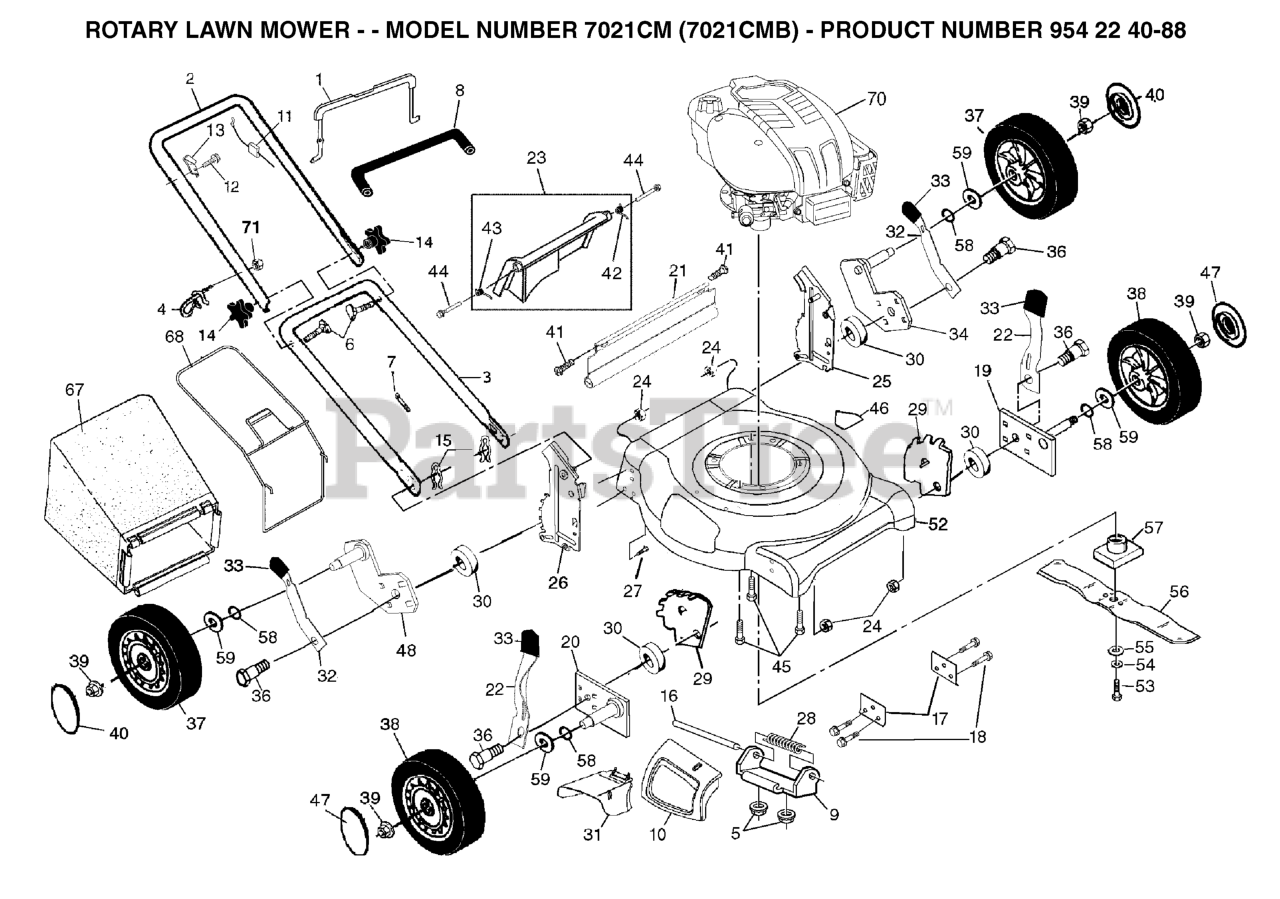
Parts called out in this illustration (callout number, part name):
1	CONTROL BAR
2	UPPER HANDLE, WITH GRIP
3	HANDLE.LOWER.GREY
4	ROPE, GUIDE
5	LOCKNUT.NYLOC.1/4-20
6	HANDLE BOLT
7	TIE GUIDE
8	GRIP.HANDLE.FOAM
9	BRACKET.ASM.HOUSING.EZ.MUL
10	RP DOOR.MULCH.21".REAR.PUSH.GR
11	ENGINE ZONE CONTROL CABLE
13	BRACKET
14	KNOB.HANDLE.STAR.HUSQ.GRAY
15	HAIRPIN COTTER
16	ROD.HINGE.COMBI-C
17	SUPPORT BRACKET
18	SCREW 1/4X20
19	AXLE ARM ASSY LF
20	AXLE ARM ASSY
21	REAR SKIRT
22	REPL BY 532 1683-60
23	KIT.REAR.DOOR.21.DOMED.
24	NUT.CENTERLOCK.5/16-
25	HANDLE BRACKET ASSEMBLY, LEFT
26	HANDLE.BRKT.ASSY.RIGHT.BLACK
27	SCREW
28	TORSION SPRING
29	WHEEL BRACKET ADJUSTER
30	SPACER.34X1.38X.22
31	DEFLECTOR.CLIPPING.21.GREY
32	SELECTOR SPRING, REAR
33	SELECTOR KNOB
34	AXLE ARM ASSY 10"
36	SHOULDER BOLT
37	WHEEL.10X2.PR.HITRAC.BLACK
38	WHEEL 8 X 2 BLACK BALL BEARING
39	HEX FLANGE LOCKNT
40	HUBCAP.10.MAG.SILVER
41	HINGE SCREW
42	SPRING (LH)
43	SPRING (RH)
45	BOLT 3/8-16X1-1/8
46	DECAL HYT
47	HUBCAP
48	ARM ASM AXLE 10"
52	HOUSING ASSEMBLY
53	SCREW, HEX HD 3/8-24 X 1-3/8
54	LOCKWASHER
55	WASHER,HARDEN
56	BLADE.21.PUSH/RWGD/FWG
57	BLADE ADAPTER
58	O-RING
59	WASHER.FLAT.1/2
67	GRASS BAG
68	FRAME, GRASS BAG
71	NUT
